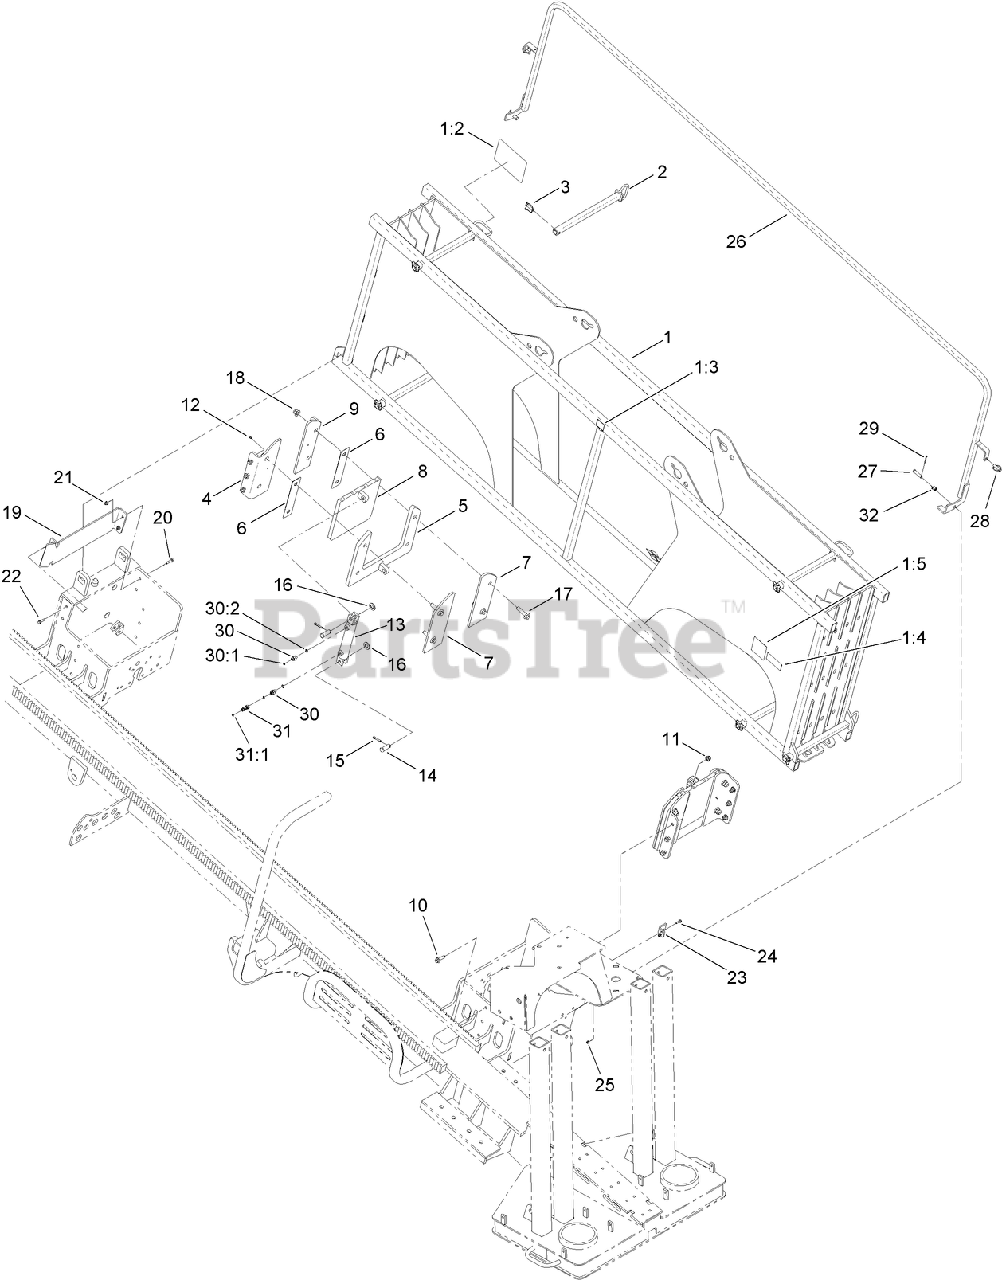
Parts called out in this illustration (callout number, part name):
1	ROD BOX ASM
1:3	DECAL-WEIGHT, ROD BASKET
1:4	DECAL-WARNING, CRUSHING
1:5	DECAL-DANGER, ENTANGLEMENT
2	PIN-ROD BOX
3	PIN-KLIK
4	PLATE-MOUNTING, ELEVATOR
5	PLATE-ELEVATOR
6	PLATE-SHIM, ELEVATOR
7	PLATE-SUPPORT, ELEVATOR
8	MOUNT-CYLINDER, ELEVATOR
9	PLATE-MOUNTING, ELEVATOR
10	SCREW-HHF
11	NUT-HHF, LOCK
12	FITTING-GREASE
13	HYD CYLINDER ASM
14	PIN-CLEVIS
15	PIN-COTTER
16	WASHER-FLAT
17	SCREW-HHF
18	NUT-HHF
19	DEFLECTOR
20	SCREW-HHF
21	NUT-LOCK, HHF
22	SCREW-HHF
23	BRACKET-ANGLE, GUARD
24	SCREW-HHF
25	NUT-FLANGE, NI
27	PIN-CLEVIS
28	PIN-SNAP RING
29	PIN-COTTER
30	FITTING-STRAIGHT
30:1	O-RING
30:2	O-RING
31	FITTING-STRAIGHT
31:1	O-RING
32	SPACER-TUBULAR
